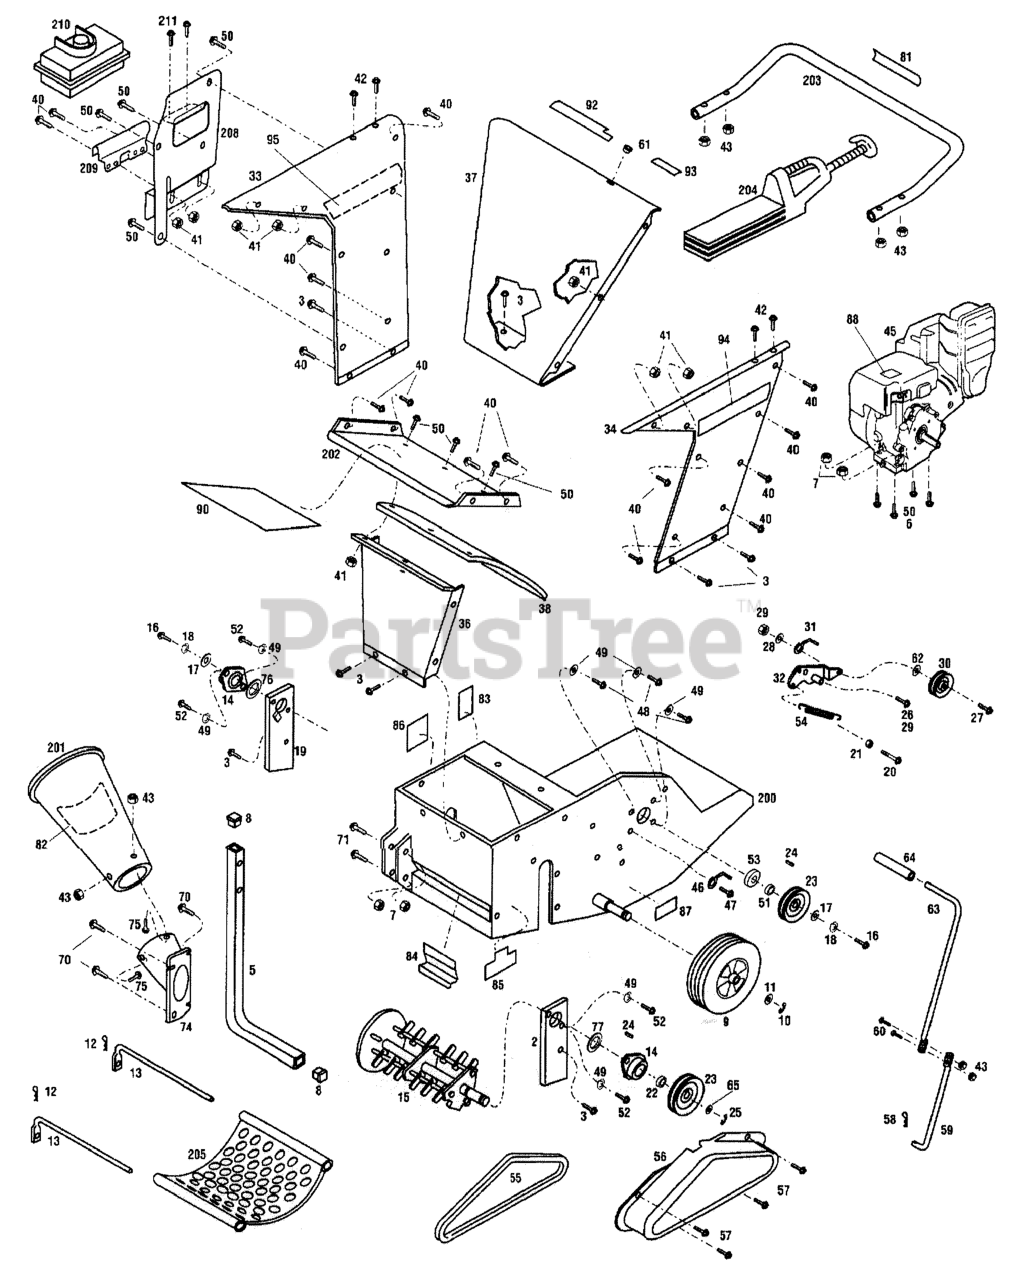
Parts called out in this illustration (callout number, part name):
2	Assembly, Left Closure
3	Flange Screw, 5/16-18 x 1/2
5	Front Stand
6	Flange Screw, 5/16-18 x 1-1/2
7	Flange Nut, 5/16-18
8	Plug Cap
10	Ring, Retaining
11	Washer, Flat
12	Clip, Hairpin
13	Rod, Retainer
15	Cylinder Assembly
16	Screw, Hex 3/8-24 x 1-1/4
17	Washer, Flat
18	Washer, Lock
19	Assembly, Right Closure
20	Screw, Hex 5/16-18 x 1-1/4
21	Nut, Hex 5/16-18
22	Collar, Locking
24	Key, Square
25	Ring, External Retaining
26	Bolt, Shoulder 3/8-16
27	Screw, Hex 3/8-16 x 1-3/4
28	Washer, Flat
29	Nut, Toplock
30	Pulley, Idler
31	Guide, Belt
32	Assembly, Idler Arm
33	Panel, Right
34	Panel, Left
36	Panel, Front Bottom
37	Panel, Back
38	Flap, Rubber
40	Screw, Flange 1/4-20 x 1/2
41	Nut, Flange 1/4-20
42	Screw, Flange 1/4-20 x 1-1/2
43	Nut, Toplock 1/4-20
45	Engine *
46	Guide, Belt
47	Screw, Flange 5/16-24 x 3/4
48	Screw, Hex 5/16-24 x 5/8
49	Washer, Lock
50	Screw, Flange 1/4-20 x 5/8
51	Shim, Drive Sheave
52	Screw, Flange 5/16-18 x 3/4
53	Spacer, Drive Shaft
54	Spring, Extension
56	Cover, Belt
57	Screw
58	Pin, Cotter
59	Rod, Lower Clutch
60	Screw, Hex 1/4-20 x 3/4
61	Bushing, Snap
62	Washer, Flat
63	Rod, Upper Clutch
64	Grip, Plastic
65	Washer, Thrust
70	Screw, Flange 5/16-18 x 7/8
71	Screw, Flange 5/16-18 x 1-3/4
74	Base, Chipper Chute
75	Bolt, Carriage
76	Seal, Dust
77	Seal, Dust
81	Decal, Combustible Material
82	Decal, Danger
83	Decal, Danger
84	Decal, Front Hand Hazard
87	Decal, Warning
88	Decal, Warning Hot Surface
90	Decal, Instructions
92	Decal, Panel
94	Decal, Logo
200	Assembly, Mainframe
201	Assembly, Chute
202	Assembly, Panel
203	Assembly, Handlebar
204	Kit, Leaf Tamper
205	Kit, Screen 3/4"
208	Bracket, Upper Mounting
209	Bracket, Lower Mounting
210	Tank, Fuel
211	Screw, Plastite
